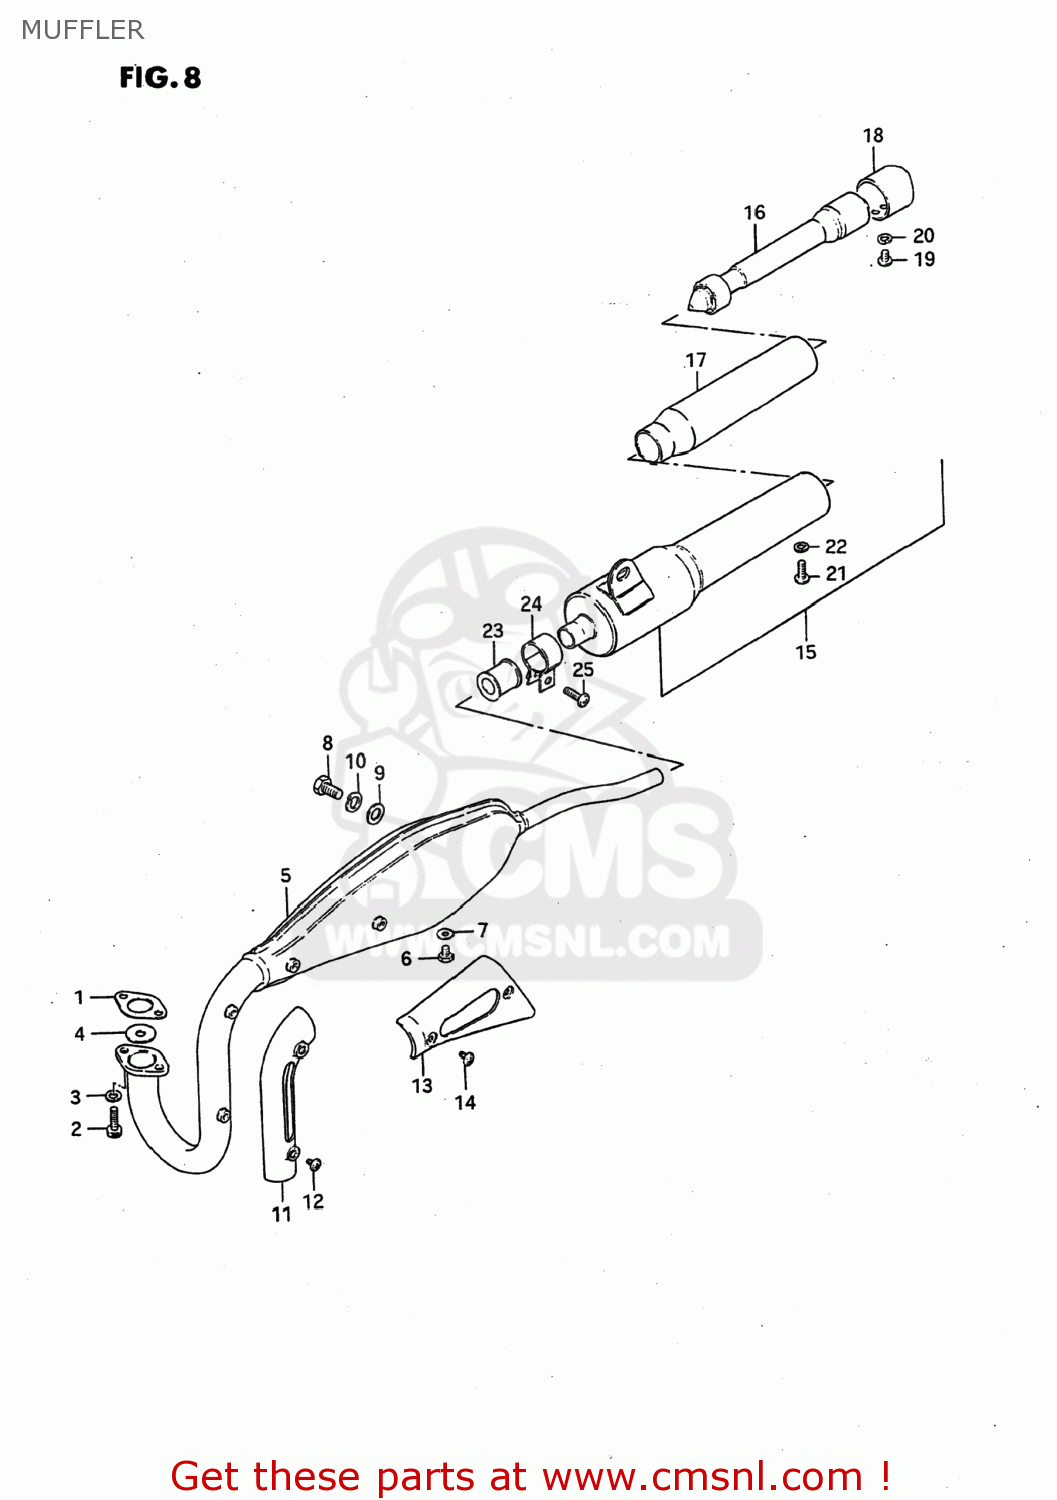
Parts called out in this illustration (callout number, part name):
1	GASKET,EXHAUST PIPE (NAS)
2	BOLT
3	WASHER,LOCK
4	PLATE,EXHAUST PIPE
5	MUFFLER ASSY
6	BOLT
7	WASHER
8	BOLT
9	WASHER (8.2X20X1.6)
10	LOCK WASHER
11	COVER,EXHAUST PIPE
12	SCREW
13	COVER,MUFFLER
14	SCREW
15	MUFFLER ASSY,2ND
16	TUBE,CLEAN OUT
17	SHELL,ARRESTER
18	CUTTER,MUFFLER TAIL
19	SCREW
20	WASHER,LOCK
21	SCREW
22	WASHER,LOCK
23	CONNECTOR,MUFFLER
24	CLAMP
25	SCREW
